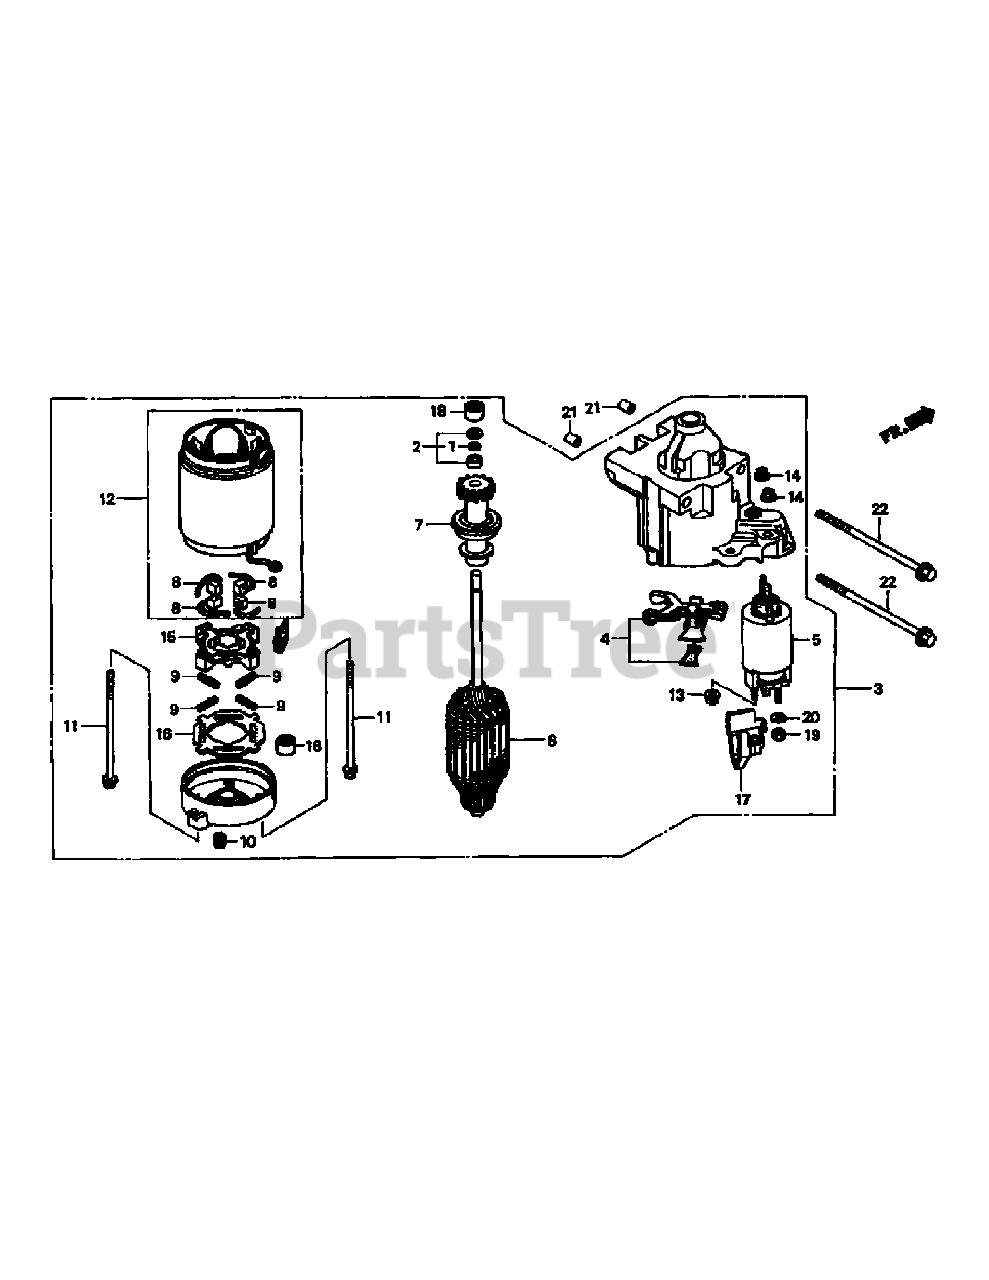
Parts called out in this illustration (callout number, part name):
2	Clutch Stop Collar Set
3	Starter Motor Assy.
4	Pinion Drive Lever
5	Magnet Switch Assy.
7	Overrunning Clutch
9	Brush Spring
11	Through Bolt
13	Hex Nut (8mm)
14	Flange Nut (5mm)
15	Brush Holder
16	Brush Holder Insulator
17	Terminal Cover
19	Hex Nut (8mm)
20	Spring Washer (8mm)
21	Dowel Pin
22	Flange Bolt (8x110)
